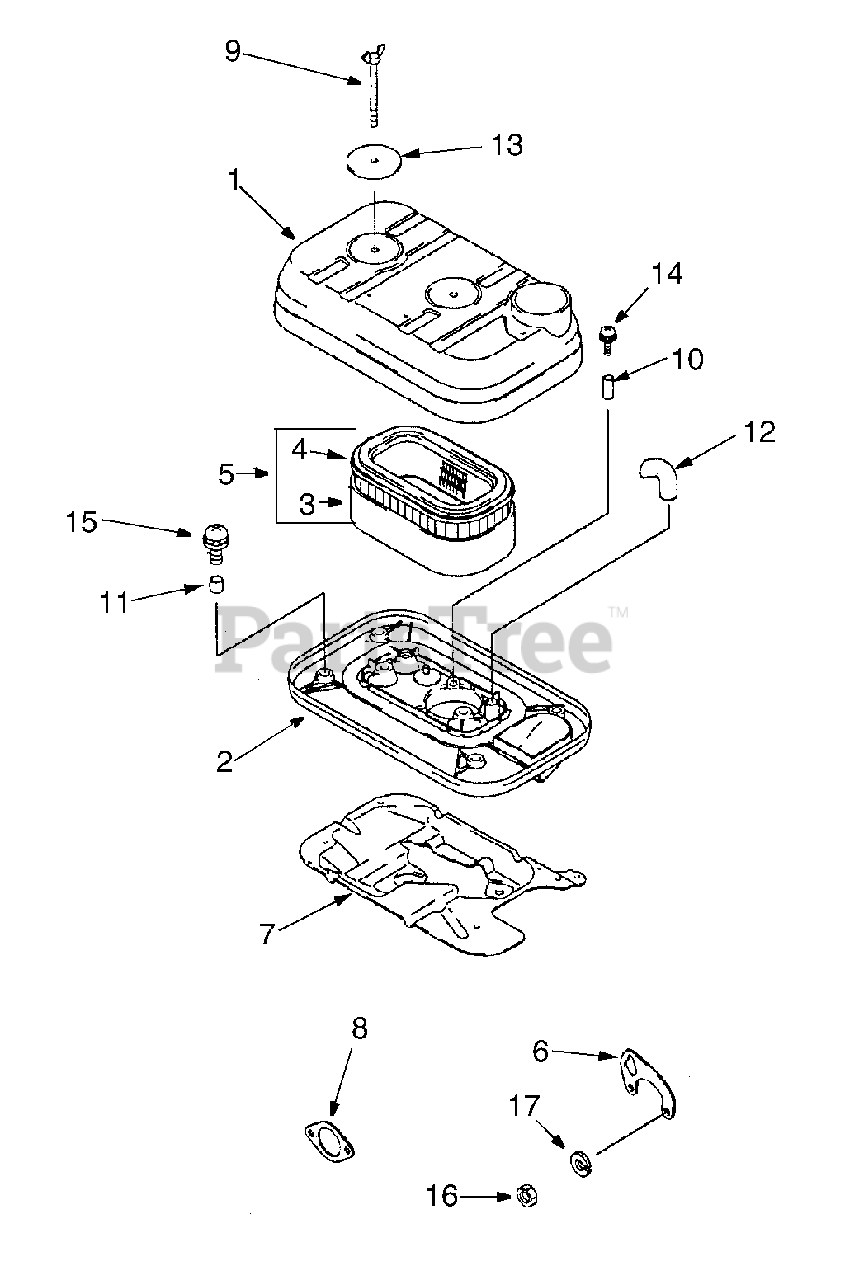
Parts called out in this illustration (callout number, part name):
1	Case, Air Filter
2	Base, Air Filter
3	Element, Foam
4	Element, Air Filter
5	Air Filter Ass'y.
7	Bracket, Air Filter
8	Gasket, Muffler
10	Collar, 5.1 x 6.3 x 14
11	Collar, 6.2 x 7.8 x 7.5
14	Screw, Pan, WSP
16	Nut, Hex
17	Washer, Spring
